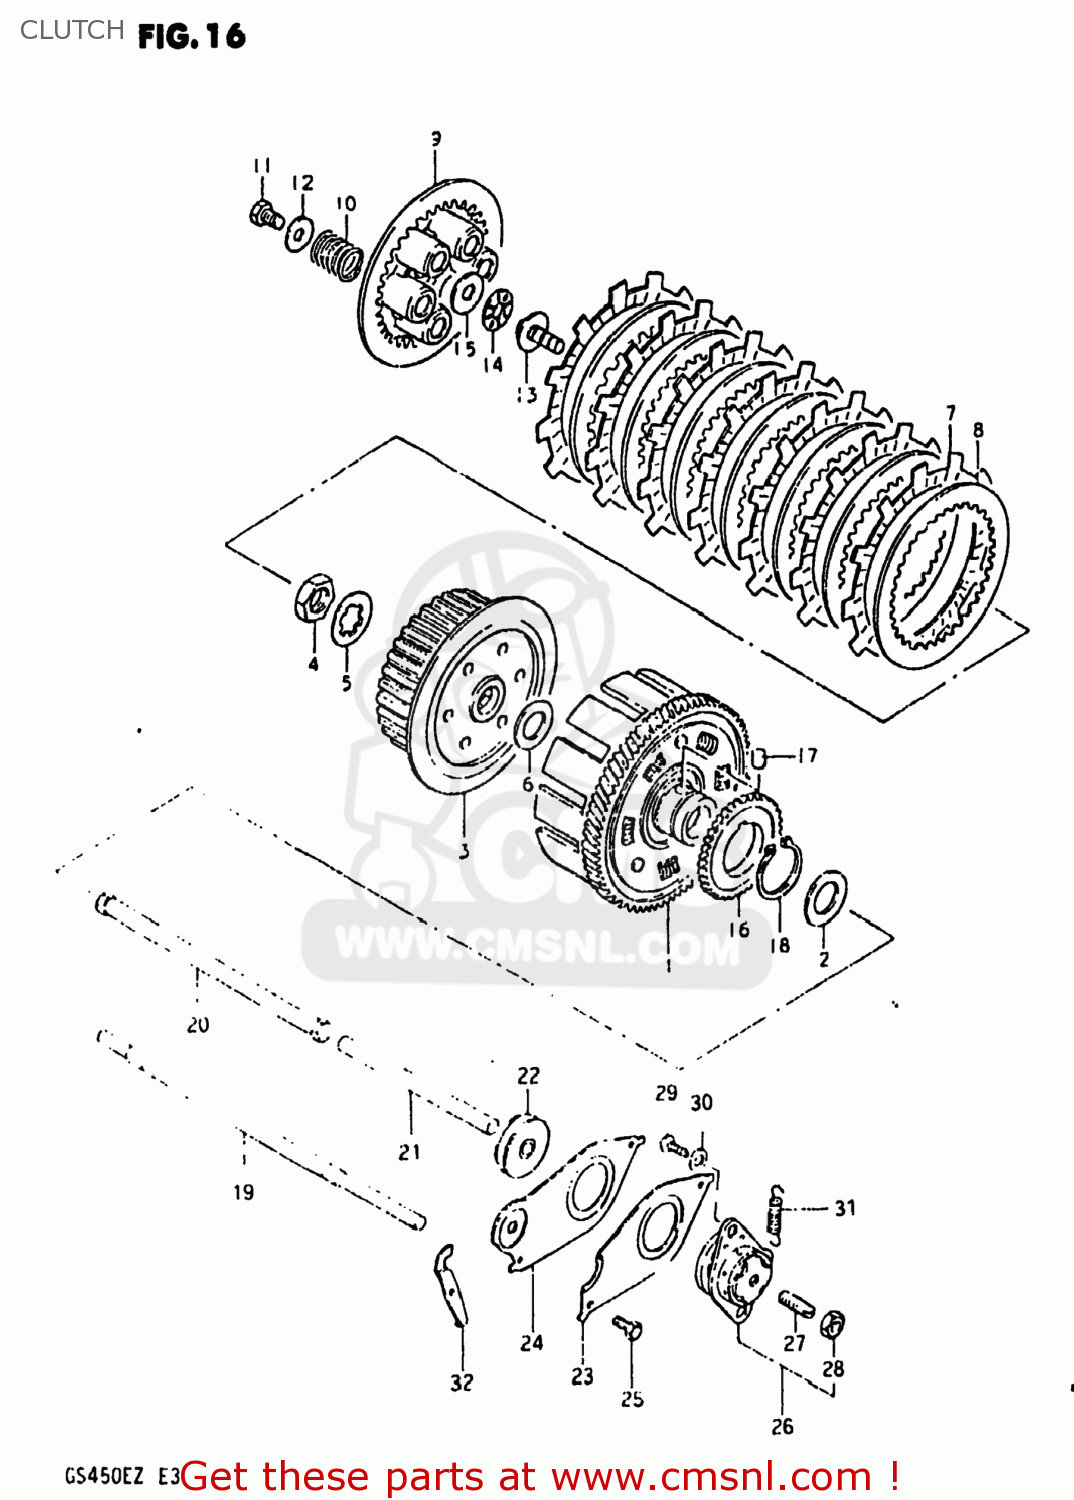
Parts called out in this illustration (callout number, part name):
1	GEAR ASSEMBLY,PRIMARY DRIVE
2	WASHER
3	HUB,CLUTCH SLEEVE
4	NUT (20MM)
5	WASHER,LOCK
6	WASHER(20X44X3)
7	PLATE,CLUTCH DRIVE (MCA)
8	PLATE,CLUTCH DRIVEN (NAS)
9	DISC,CLUTCH PRESSURE
10	SPRING
11	BOLT, UPPER
12	WASHER
13	PIECE,CLUTCH PUSH
14	BEARING(15X28X2)
15	WASHER
16	GEAR,OIL PUMP DRIVE
17	PIN(6X6)
18	CIRCLIP
19	ROD,CLUTCH PUSH
20	ROD,CLUTCH PUSH
21	ROD,CLUTCH PUSH
22	SEAL,OIL(6X34X8)
23	PLATE,CLUTCH PUSH ROD
24	PLATE,CLUTCH PUSH ROD
25	BOLT
26	SCREW ASSEMBLY,CLUTCH RELEASE
27	SCREW
28	NUT 6MM
29	SCREW
30	WASHER
31	SPRING
32	GUIDE,PUSH ROD OIL SEAL
